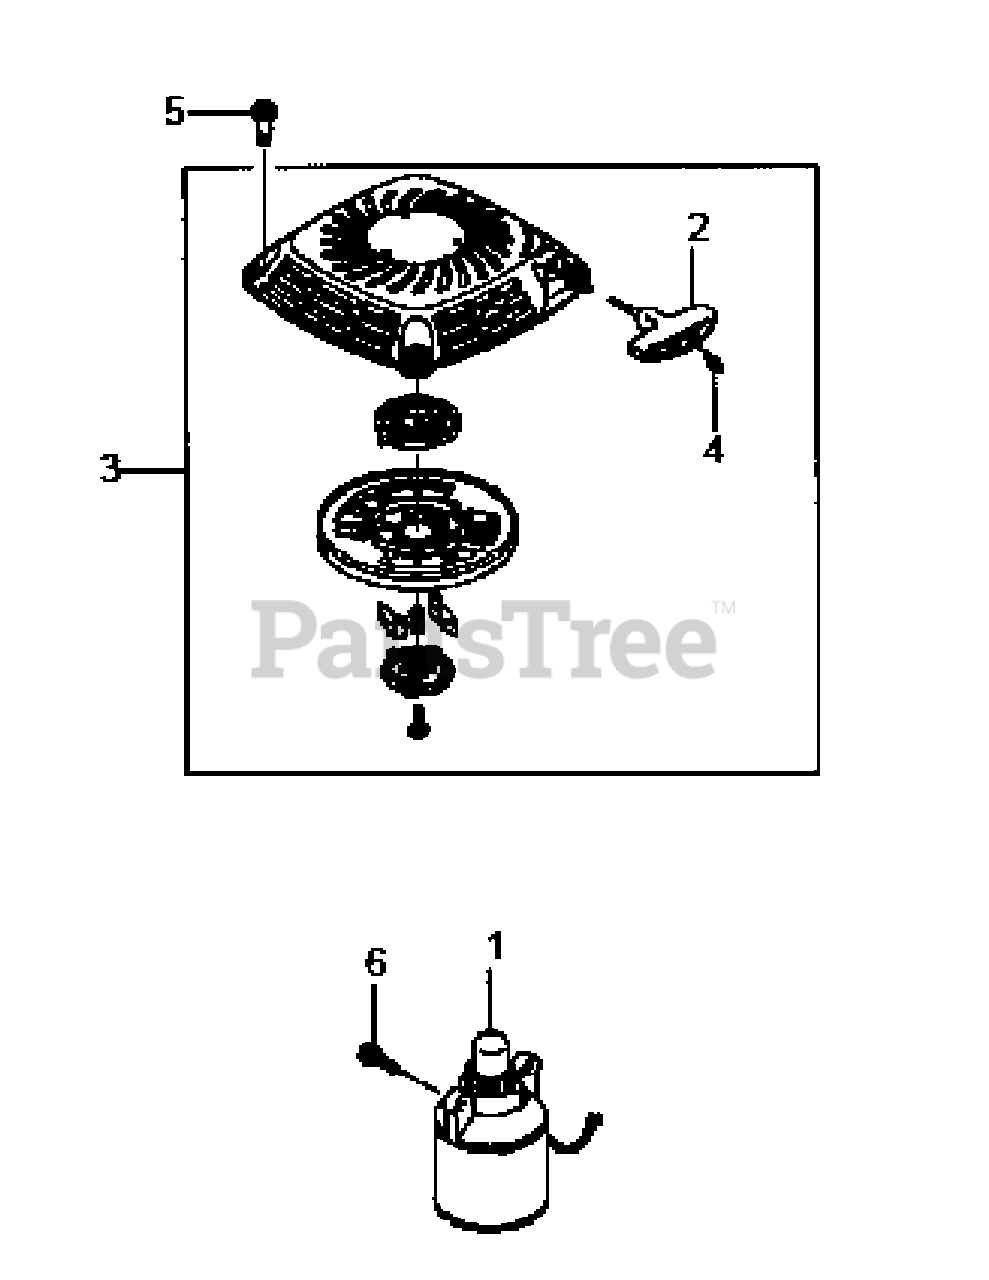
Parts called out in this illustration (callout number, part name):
1	Electric Starter
3	Recoil Starter
5	Bolt, M6
6	Flanged Bolt
